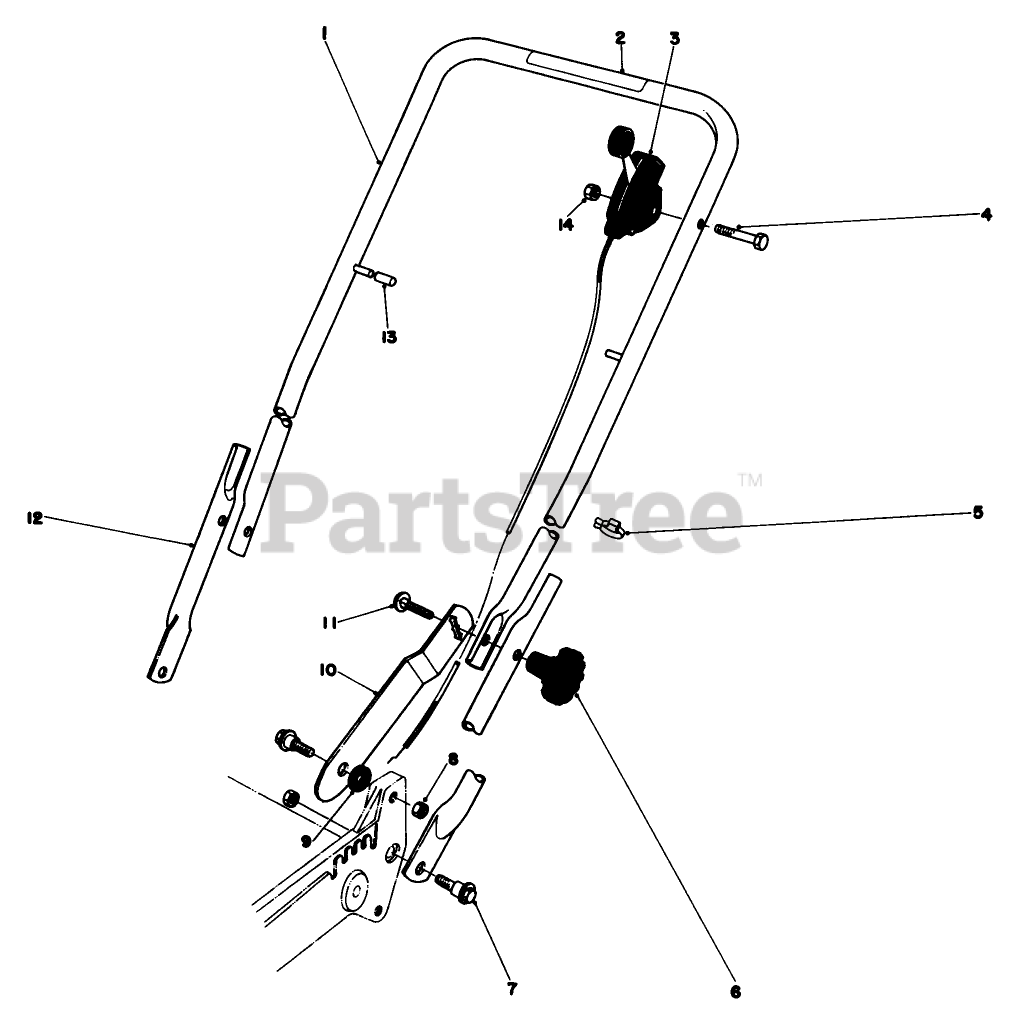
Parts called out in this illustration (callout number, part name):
4	SCREW-HH
5	BOWDEN CLIP
9	SPACER
11	BOLT-CAR
